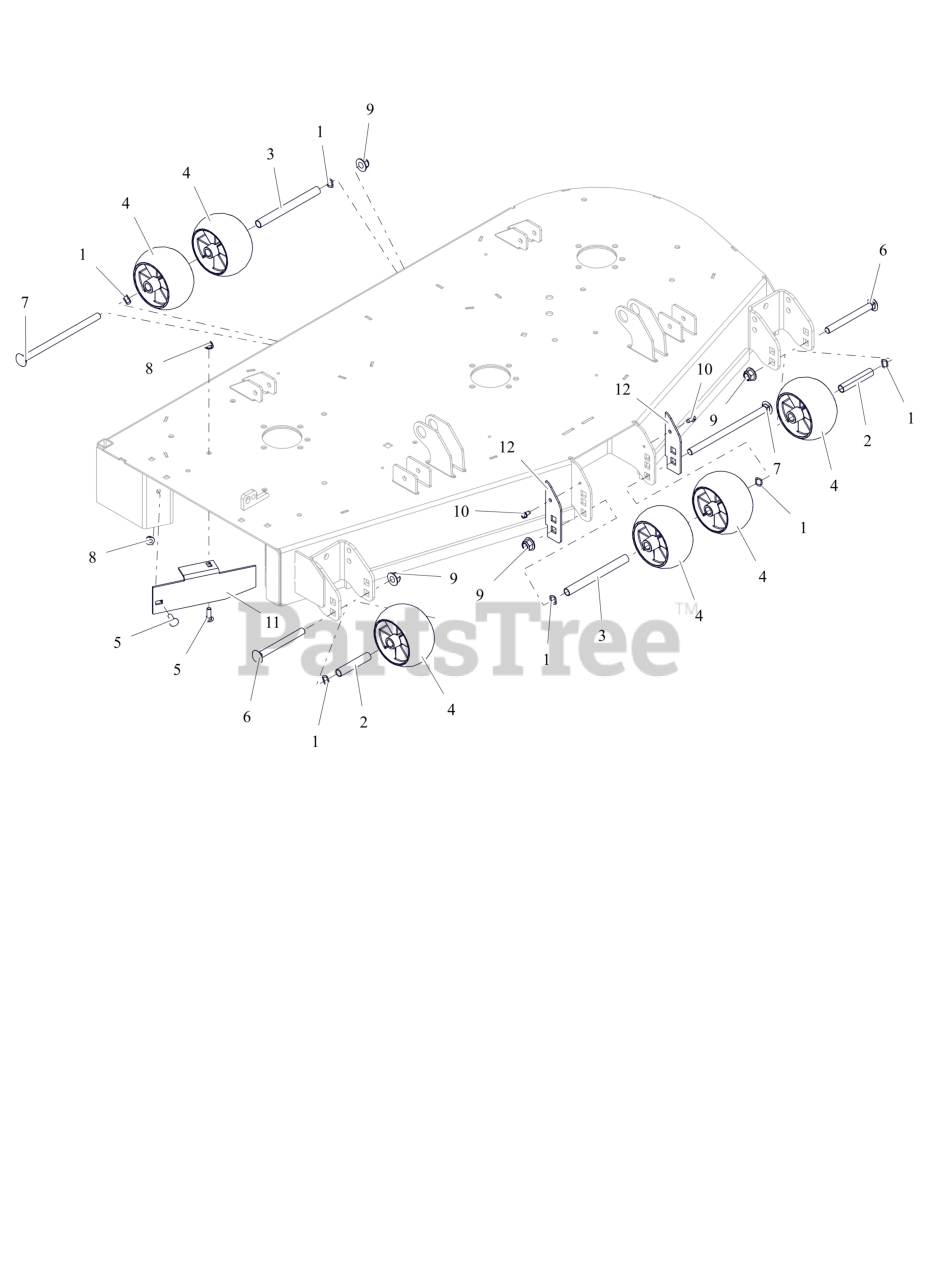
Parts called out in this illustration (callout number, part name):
1	WAVE WASHER .531X.781X.125FH
2	SPACER, .510X.625X3.35
3	SPACER, .510X.625X6.50
4	ANTI-SCALP WHEEL - 5X3 CTR
5	BLT,RHSN .31-18X1.00 G5 ZCC
6	BLT, RHSN .50-13X5.00 G5 ZCC
7	BLT, RHSN .50-13X8.50 G5 ZCC
8	NUT,LK-NYL-FLG .31-18 G5ZC120
9	NUT,NYL-FLG .50-13 GF ZCC
10	SCR-TAP .25-20X.50 HWH ZCC
11	BAFFLE, DISCHARGE, 52"
12	PLATE, ANTI SCALP WHEEL PLATE CE (ORANGE)
